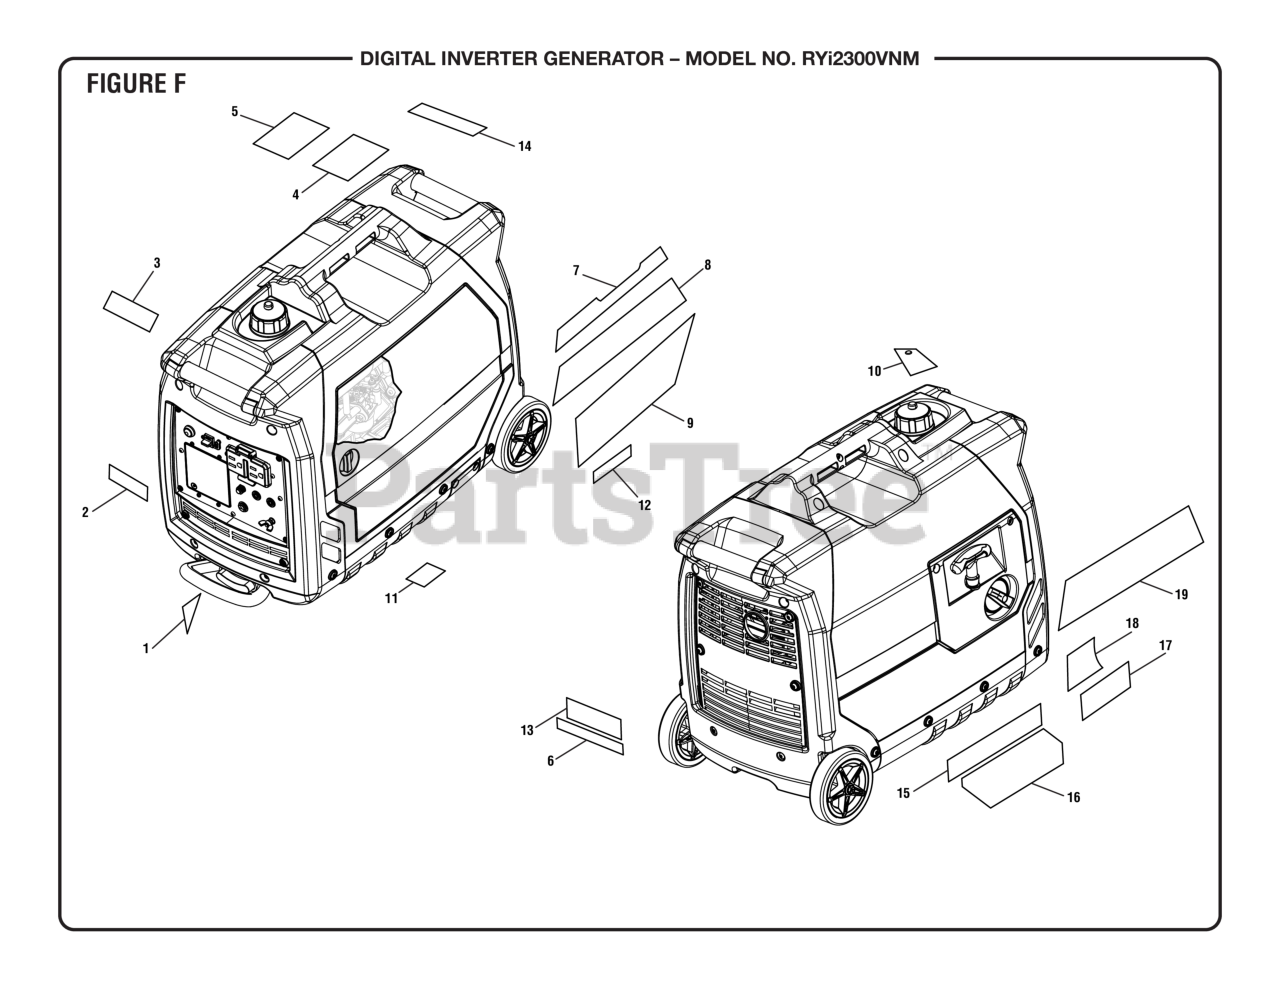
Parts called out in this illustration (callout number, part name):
1	Button Handle Release Label
2	Logo Label
3	Fuel Stabilizer Label
4	CPSC Danger Label
5	Danger Label
6	Ground Warning Label (En/Fr)
7	Fire Distance Label
8	Performance Label (Maintenance Door)
9	Inquiries Label
10	Warning Hangtag
11	Upright Storage Label
12	Internally Placed Maintance Label
13	Combustion Label
14	Exhaust Direction Label
15	Start Label
16	Gen Control/Bluetooth Label
17	Easy Start Logo Label
18	Choke Label
19	Performance Label
